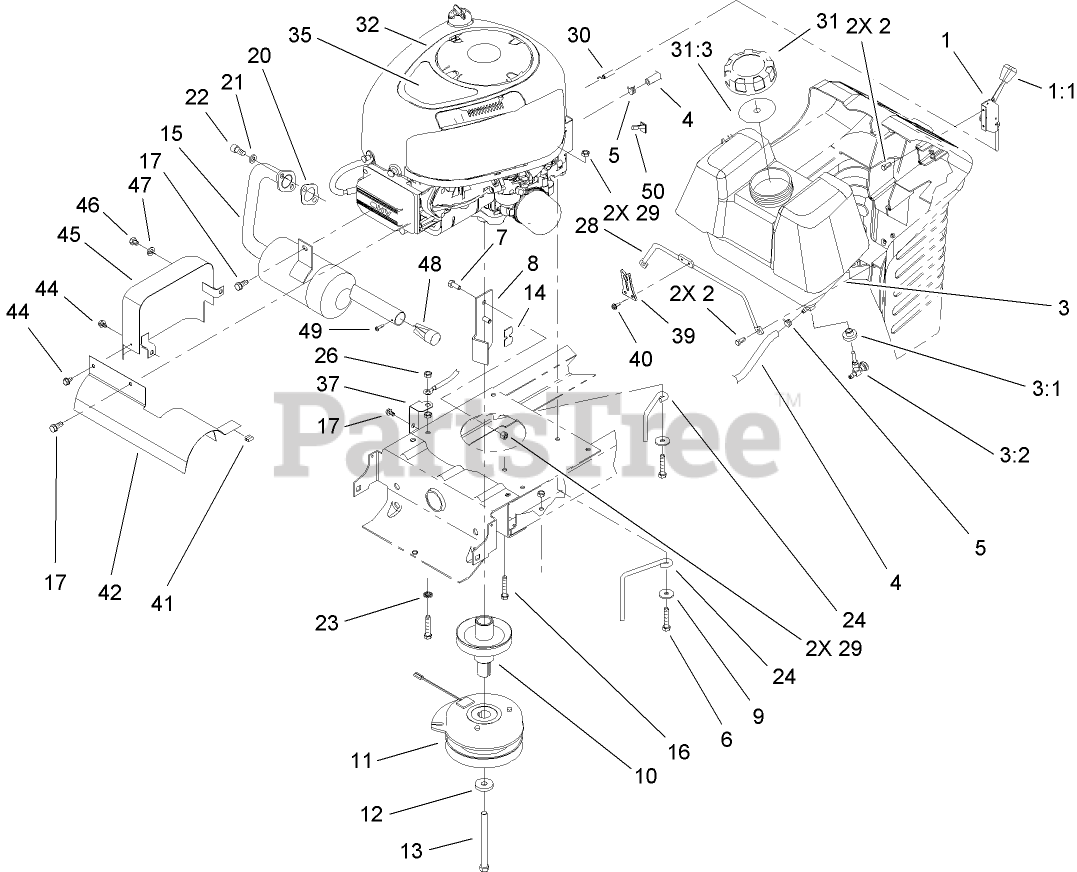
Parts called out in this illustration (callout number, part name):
1	THROTTLE CONTROL ASM
2	SCREW-SPECIAL
3	GAS TANK ASM
3:1	BUSHING
3:2	VALVE-FUEL
4	HOSE-FUEL
5	CLAMP-HOSE
6	SCREW-HH
7	SCREW-HH
8	STOP-CLUTCH
9	WASHER-PIVOT
10	PULLEY-ENGINE
11	CLUTCH-PTO, ELECTRIC
12	WASHER
13	SCREW-HH
14	BUMPER
15	MUFFLER-EXHAUST
16	SCREW-HWH, TAPTITE
17	SCREW-HWH
20	GASKET-EXHAUST
21	WASHER-LOCK
22	SCREW-HSH
23	WASHER-LOCK
24	GUIDE-BELT, RH
26	NUT-KEPS
28	ROD-TANK, GAS
29	NUT-LOCK, NI
30	THROTTLE CABLE ASM
31	GAS CAP ASM
31:3	GASKET-CAP, GAS
32	Loose Parts Package
35	DECAL-ENGINE
37	BRACKET-GROUND
39	LATCH-HOOD
40	SCREW-HWH
41	CLIP-TINNERMAN
42	SHIELD-MUFFLER
44	SCREW-HWHTF
45	HEAT SHIELD ASM
46	SCREW-HH
47	WASHER-LOCK
48	SCREEN-SILENCER, EXHAUST
49	SCREW-THD FORM, HWH
50	REDUCER-THROTTLE, RPM
